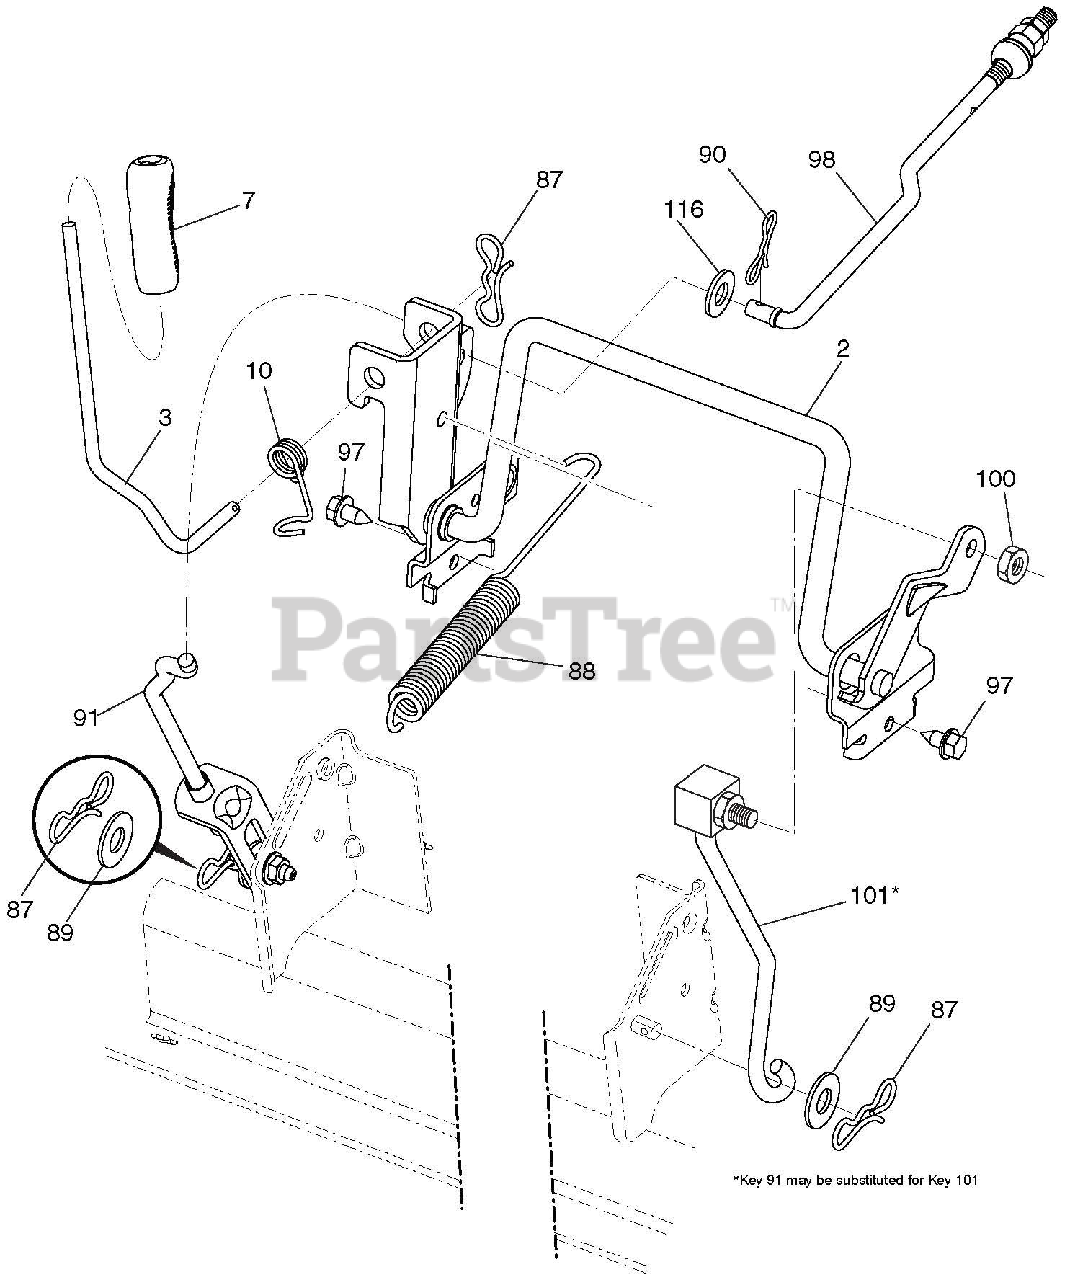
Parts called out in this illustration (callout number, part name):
2	SHAFT ASM., LIFT
3	LEVER.LIFT.HANDLE.LT
7	GRIP LEVER 5625 LD BLACK 428
10	SPRING.TORSION.HANDLE.LIFT
87	PIN.COTTER.7/16.BOW TIE LOCK
88	SPRING.LIFT ASSIST
89	WASHER.CLEAR ZINC
90	PIN.COTTER.5/16.BOW TIE LOCK
91	LINK ASM.LIFT.LH.REAR
97	SCREW.HEXWSH THDR3/8-16X3/4.BL
98	LINK ASM.SUSP.FRONT.MWR.11
100	NUT.CENTERLOCK.3/8-16 UNC.
101	LINK ASM.LIFT.FIXED.38/42/46"
116	WASHER 15/32 X 15/16 X 16 GA.
